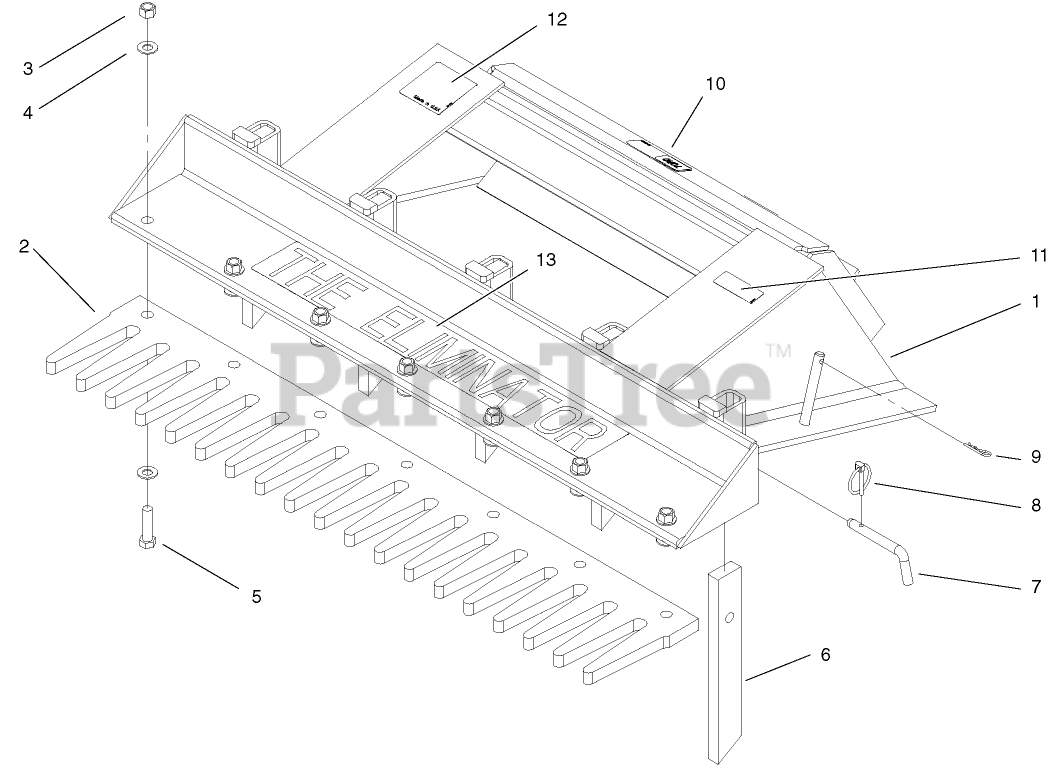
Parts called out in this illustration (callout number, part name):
1	ELIMINATOR ASM
2	Comb-Levelling
3	NUT-LOCK, NI
4	WASHER-FLAT
5	SCREW-HH
6	TOOTH
7	ASSEMBLY - PIN
8	PIN-LYNCH
9	PIN-COTTER
10	DECAL-ATTACHMENT, DINGO
11	Decal-Ce Info
12	DECAL
13	DECAL - ELIMINATOR
